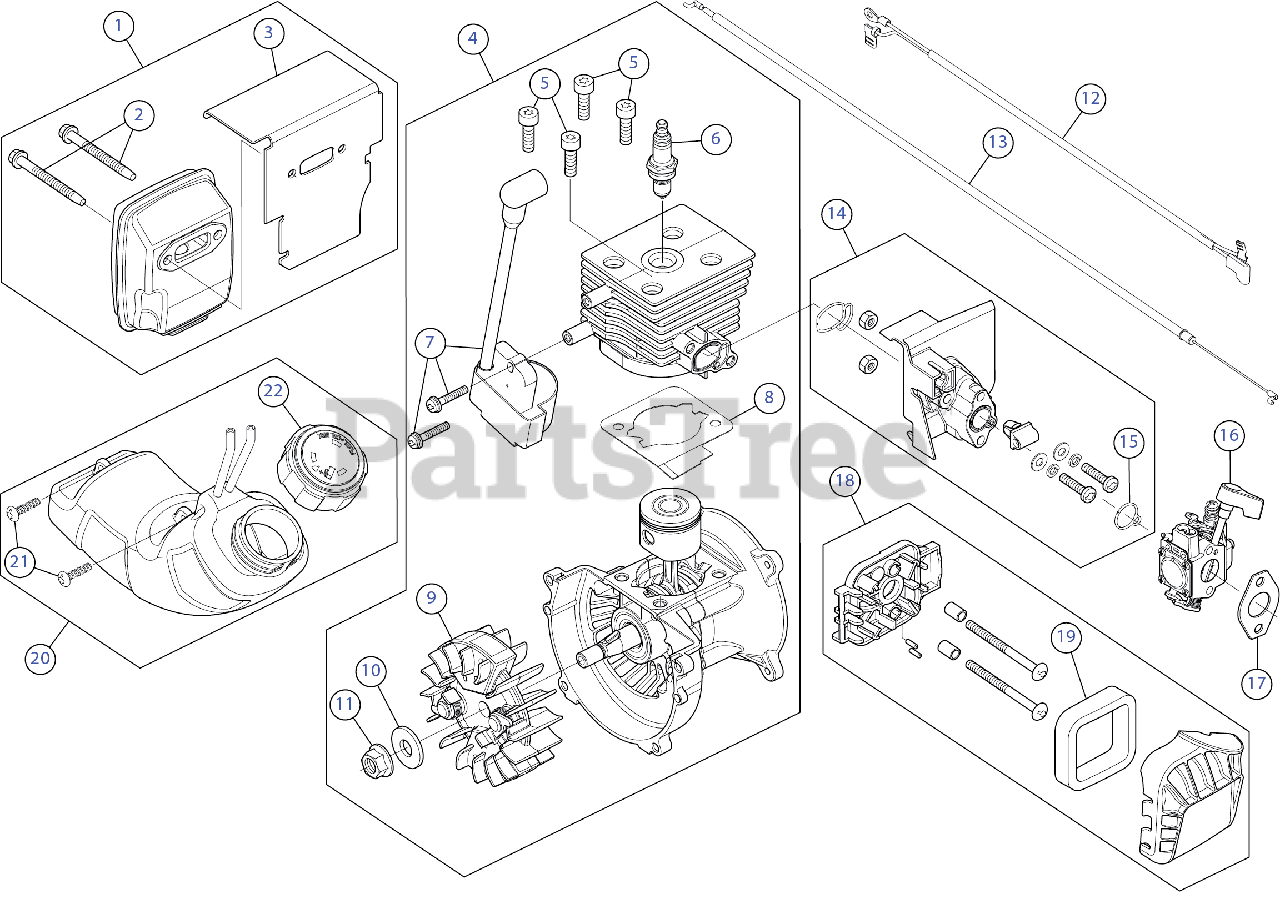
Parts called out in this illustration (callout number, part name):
1	MUFFLER ASSEMBLY 27CC
2	MUFFLER SCREW
3	MUFFLER GASKET
4	SHORT BLOCK
5	SCREW 1/4 x 20 x .8125
6	SPARK PLUG
7	MODULE ASSEMBLY
8	GASKET CYL
9	FLYWHEEL ASSEMBLY
10	WASHER .406X1.0X.095
11	NUT 3/8-24
13	THROTTLE CABLE
14	INTAKE ASSEMBLY
16	CARBURETOR ASSEMBLY
17	GASKET CARB
18	AIRCLEANER ASSEMBLY
20	FUEL TANK ASSEMBLY
21	SCREW 8-16 x 3/4
22	ASSEMBLY, FUEL CAP (RED TOP)
